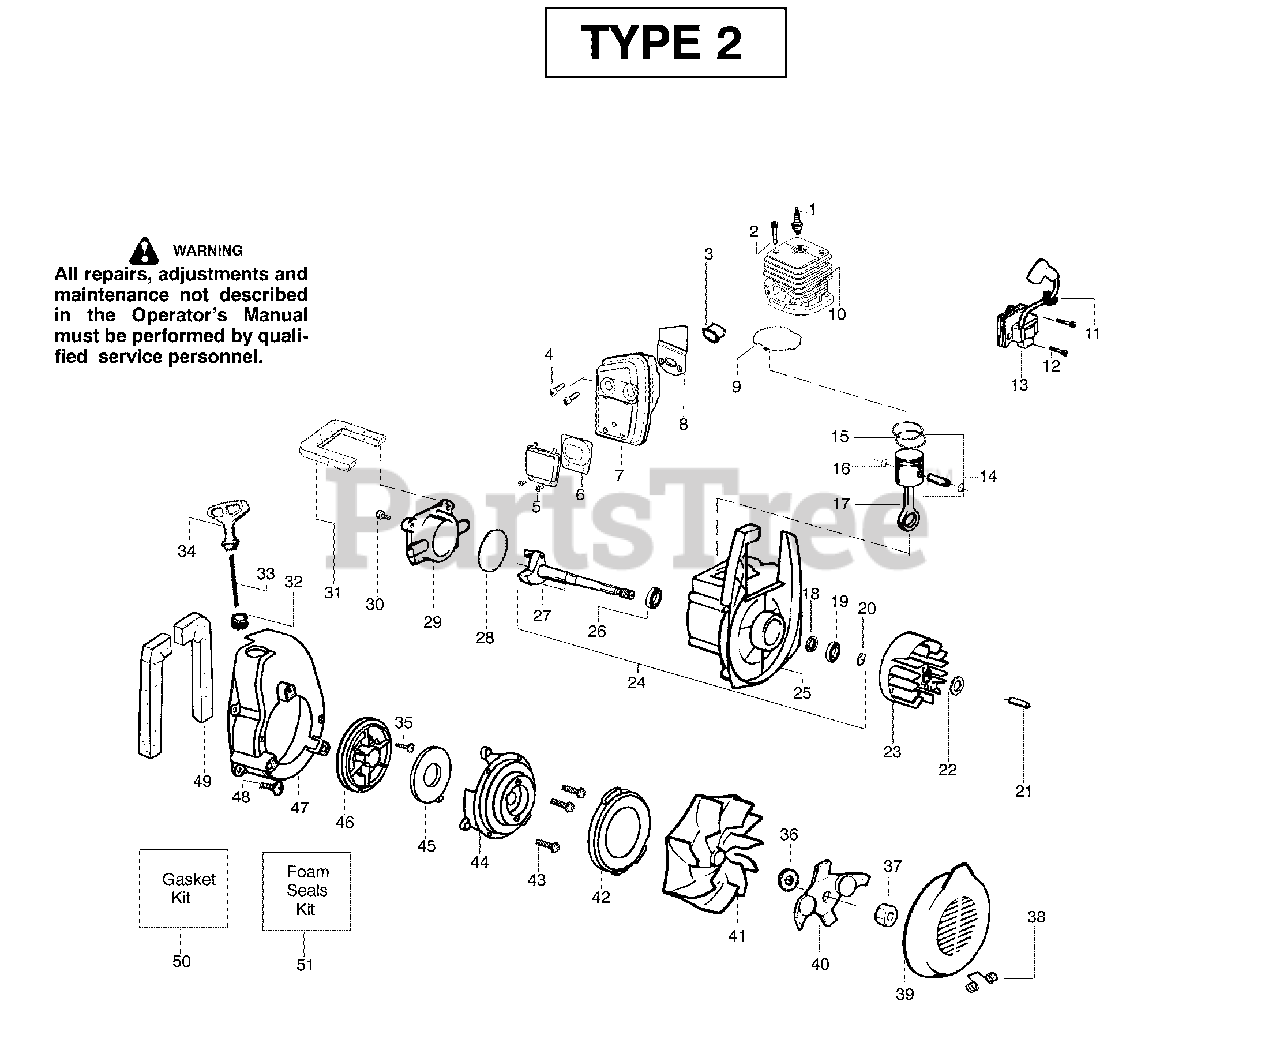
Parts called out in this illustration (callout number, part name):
1	Spark Plug (RCJ-6Y)
3	Insulator-Heat
4	Screw-Muffler-Internal
6	Kit-Spark Screen
7	Kit-Muffler
8	Gasket-Baffle (Kit)
9	Gasket-Cylinder (Kit)
10	Kit-Cylinder
11	Grommet-Ign. Module
12	Screw-Ignition Module
13	Ignition Module
14	Kit-Piston
15	Piston Ring
16	Retainer-Piston Pin
17	Assy-Connecting Rod
18	Kit-Crankcase Seal
19	Bearing-Outer
20	Retainer Ring-C'chaft
21	Spacer-Flywheel
23	Assy-Flywheel
24	Assy-Crankcase/Crankshaft
25	Assy-Crankcase
26	Bearing-Inner
27	Assy-Crankshaft
28	O-ring-C/case (Kit)
29	Cover-Crankcase
30	Screw
31	Foam-219mm (Kit)
32	Eyelet-Flange
33	Kit-Rope
34	Handle-Starter
35	Screw-Rope
36	Washer-Belleville
38	Spring-Return Cover
39	Inlet Door
40	Assy-Mulch Blade
41	Assy-Impeller
42	Seal-Ring
44	Housing-Pulley
45	Spring-Starter
46	Kit-Starter Pulley
47	Fan Housing
48	Screw
49	Foam-182mm (Kit)
50	Kit-Gasket
51	Kit-Foam Seals
